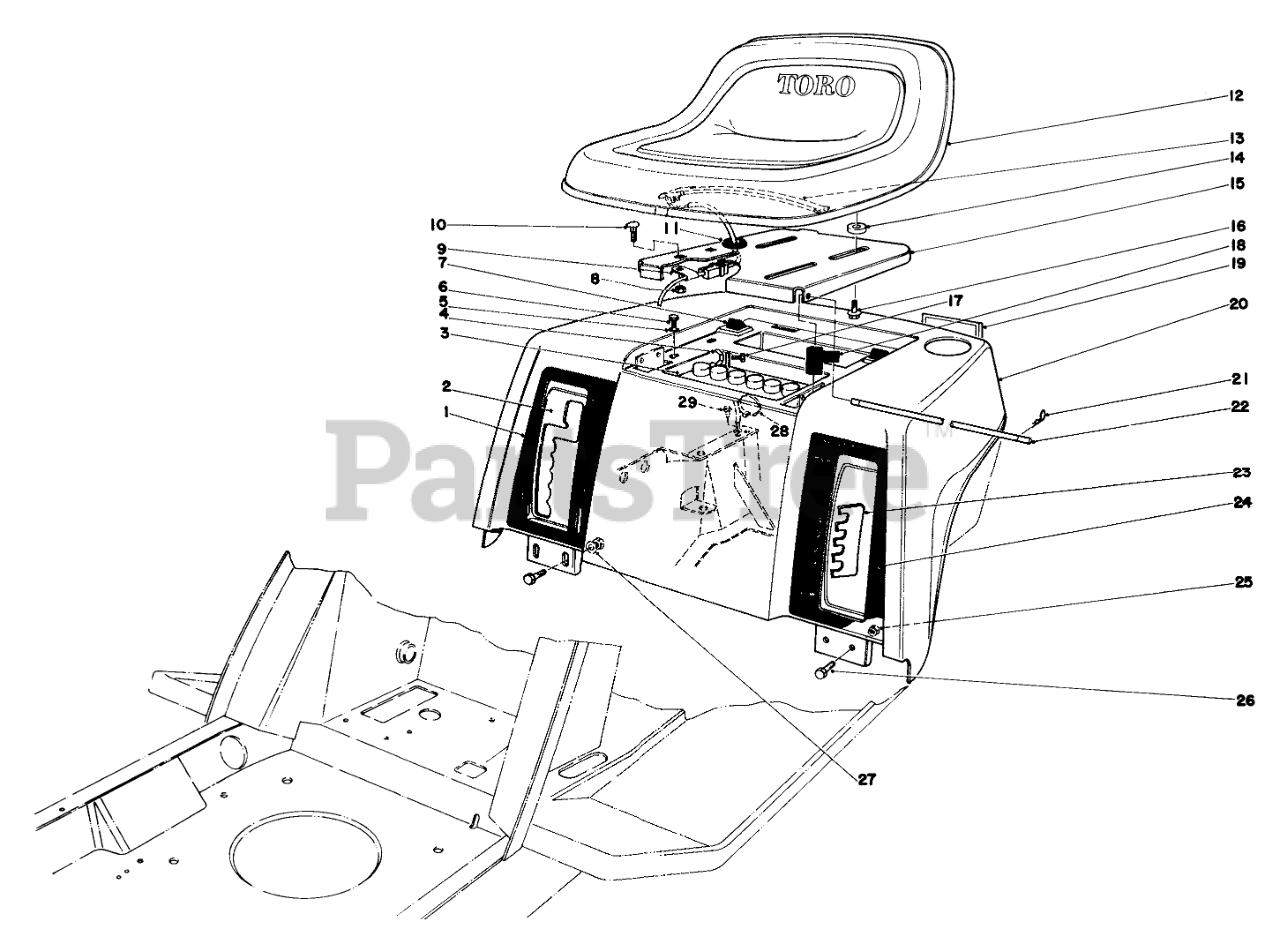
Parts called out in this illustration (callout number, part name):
1	Decal-Transmission
2	DETENT PLATE B
3	BATTERY-DRY W/CARTON
4	NUT-WING
5	WASHER
6	SCREW-HWHTF
7	SEAT BUMPER
8	NUT-KEPS
9	CLAMP
10	SCREW-CARR
11	GROMMET
12	Seat (Model #57360)
13	SWITCH-SEAT
14	SPACER-PIN, MOUNTING
15	SEAT SUPPORT R
16	SCREW-HHF
17	SCREW-HH
18	BOOT-TERMINAL
19	Reflector
20	Rear Body Assembly (Incl. Ref. #1 & 24)
21	PIN-COTTER
22	PIVOT-SEAT
23	HOC QUADRANT B
24	HOC DECAL
25	NUT-LOCK, CONE
26	SCREW-HH
27	WASHER-PLAIN
28	TIE-CABLE
29	SCREW-HWHTF
